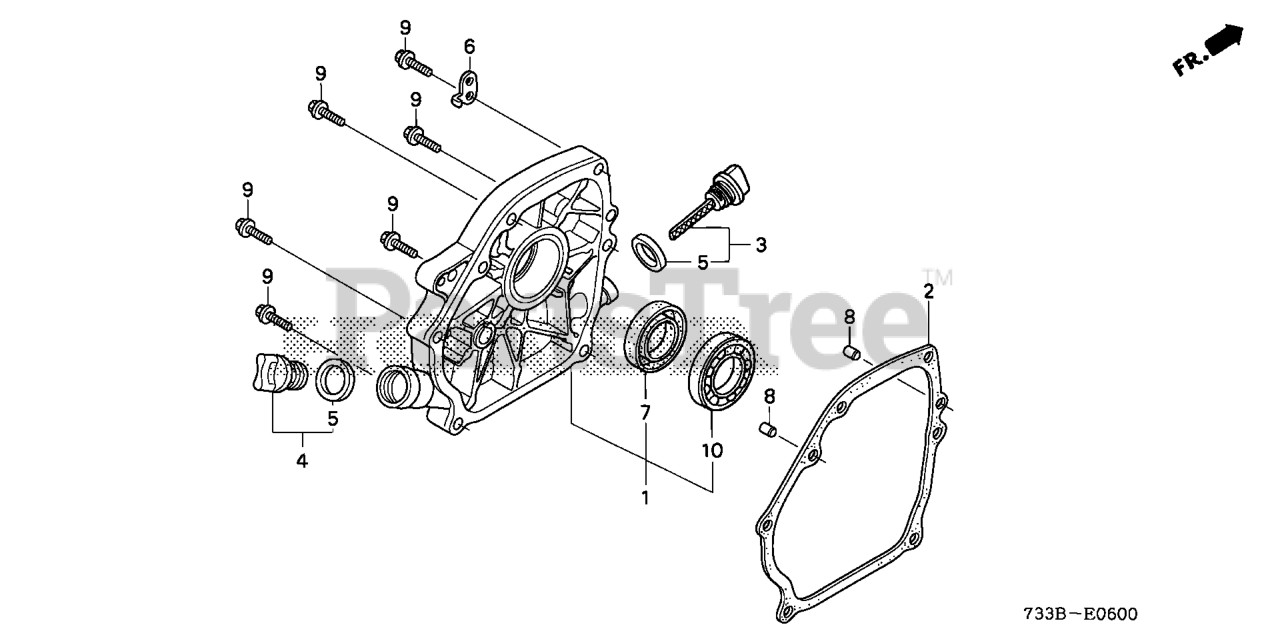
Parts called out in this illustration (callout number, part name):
1	COVER ASSY., CRANKCASE
2	GASKET, CASE COVER (NON-ASBESTOS)
2	GASKET, CASE COVER (NINGBO SIL GASKET)
3	CAP ASSY., OIL FILLER
4	CAP ASSY., OIL FILLER
5	GASKET, OIL FILLER CAP
6	STAY, WIRE CLIP (A)
7	OIL SEAL (25X41X6)
8	PIN A, DOWEL (8X14)
9	BOLT, FLANGE (8X32)
10	BEARING, RADIAL BALL (6205)
